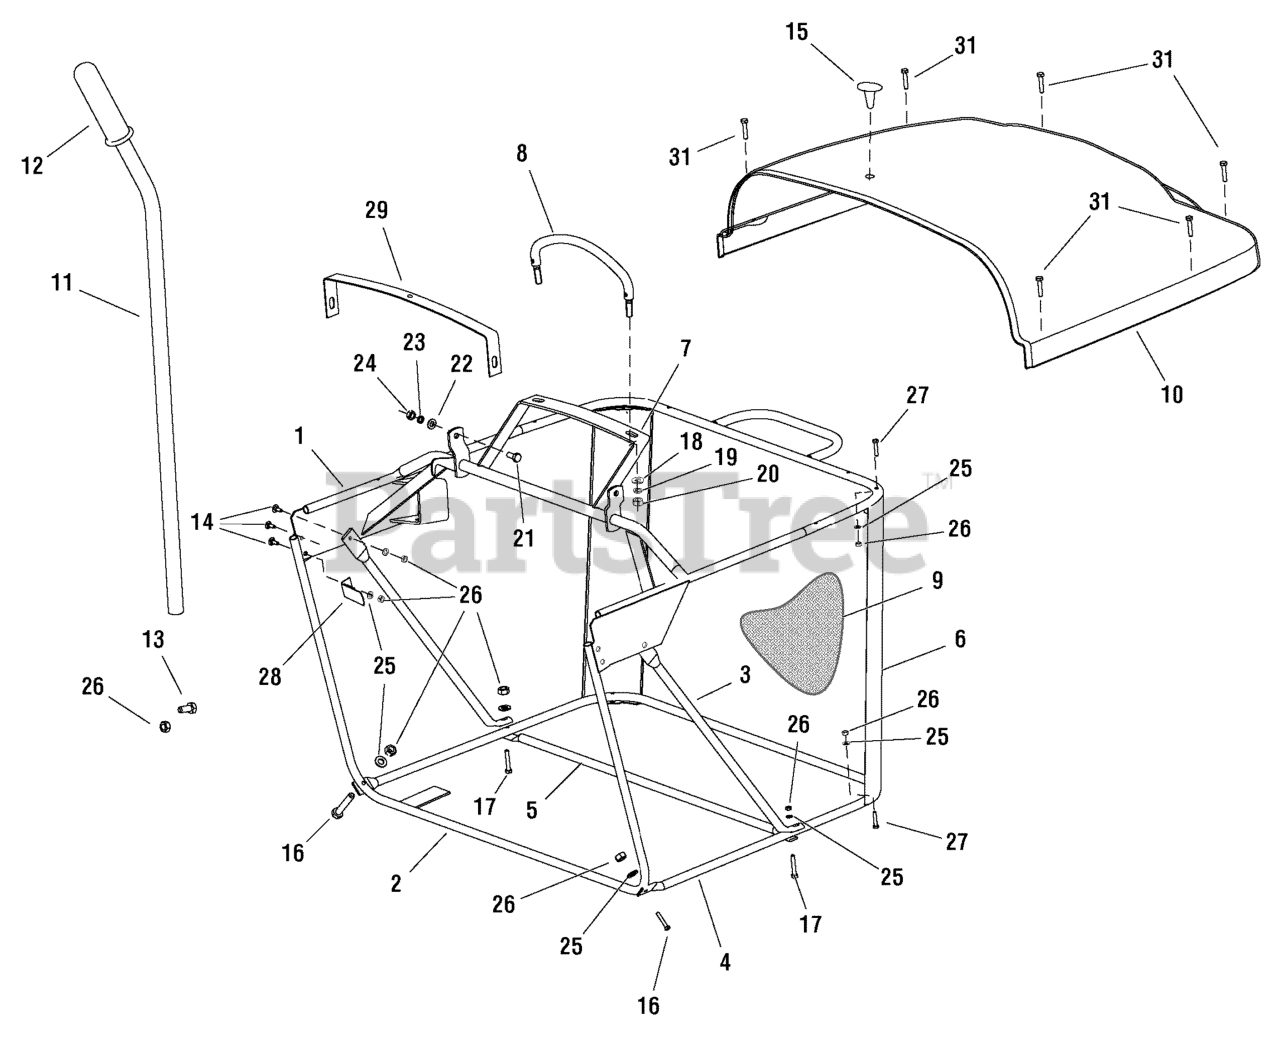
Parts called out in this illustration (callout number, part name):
1	FRAME, Top
2	TUBE, Front
4	TUBE, Bottom
5	REINFORCEMENT, L.H.
6	REINFORCEMENT, L.H.
7	REINFORCEMENT, R.H.
8	HANDLE, FULL
9	COAT, Fabric
10	TOP COLLECTOR
11	LEVER DUMPING
12	HANDLE, Rubber
13	BOLT, M5 x 12
14	BOLT, M5 x 16
16	BOLT, M5 x 30
17	BOLT, M5 x 35
18	WASHER, 10.5
19	WASHER, 10.5
20	NUT, M10
20	NUT, Flange Lock, M10
21	CAPSCREW, M8 x 40
22	WASHER, 8.4
23	WASHER, 8
24	NUT, M8
24	NUT, Flange Lock, M8
25	WASHER, 5.3
26	NUT, M5
26	NUT, DIN 6926, M5
27	BOLT, M5 x 25
28	SPRING, Flat
29	REINFORCEMENT, Top
31	CAPSCREW, 6.3 x 32
